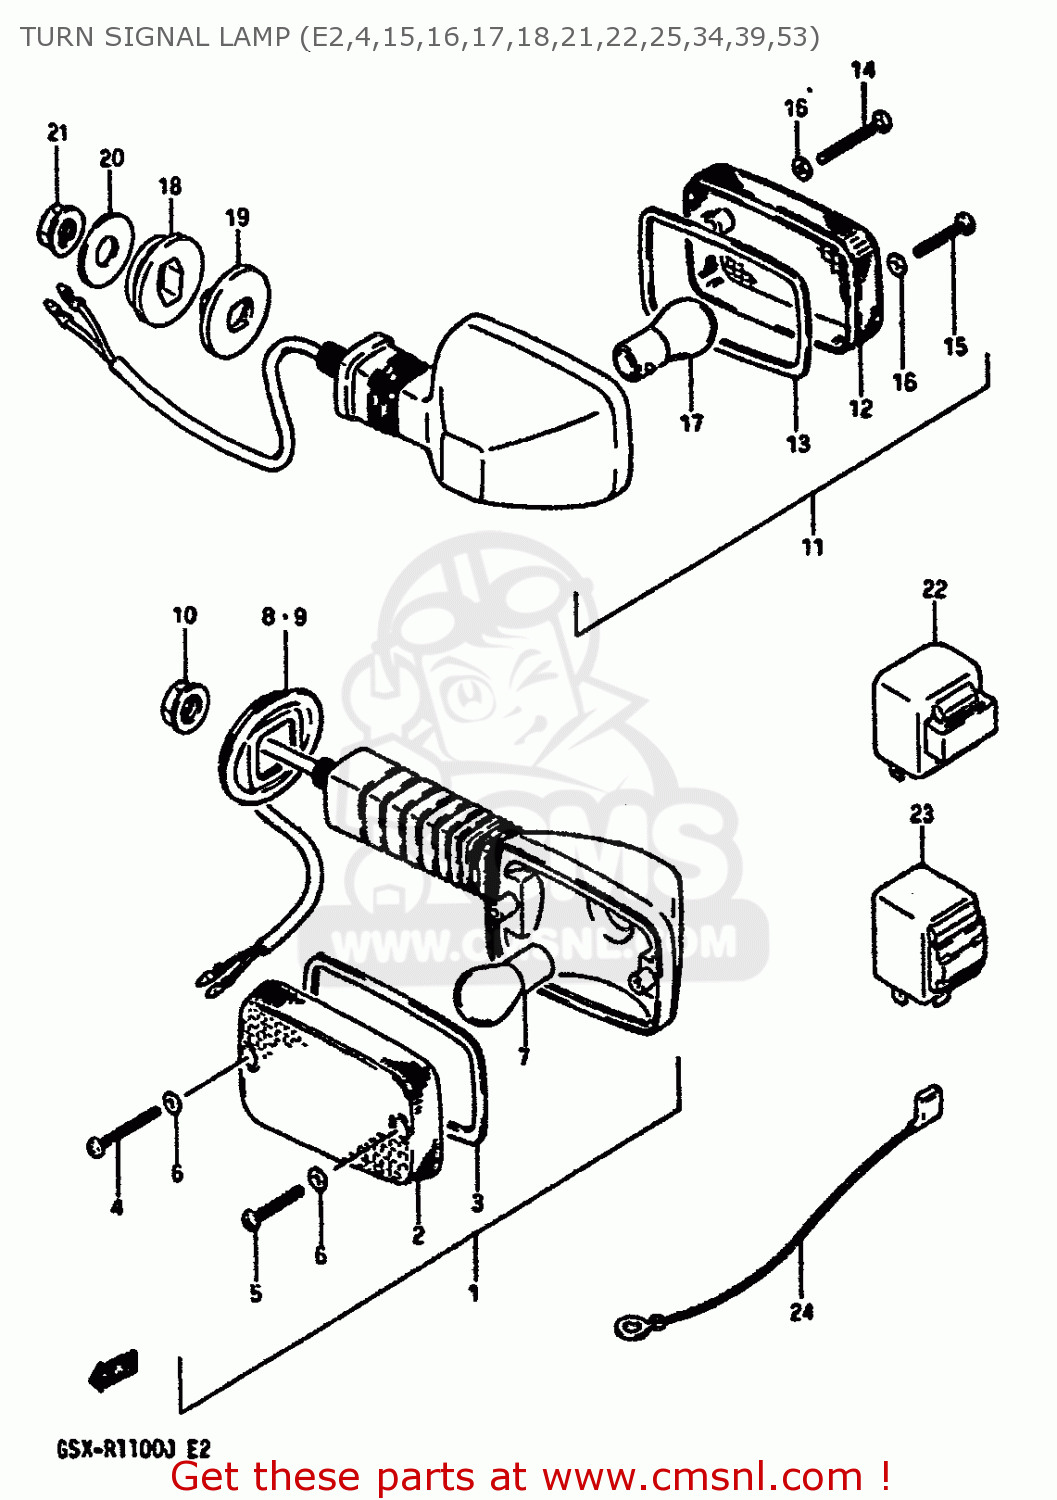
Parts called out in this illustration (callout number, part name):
1	LAMP ASSY, FRONT TURN SIGNAL
2	LENS,FR
3	GASKET (NAS)
4	SCREW,TURN SIG LENS FITTING
5	SCREW
6	GASKET
7	BULB(12V21W)
8	GROMMET, FRONT RH
9	GROMMET, FRONT LH
10	NUT
11	LAMP ASSY,REAR TURN SIGNAL
12	LENS,RR
13	GASKET (NAS)
14	SCREW,TURN SIG LENS FITTING
15	SCREW
16	GASKET (NAS)
17	BULB(12V21W)
18	CUSHION
19	SPACER
20	WASHER (10.2X27X1.6)
21	NUT
22	RELAY ASSEMBLY,TURN SIGNAL
23	RELAY ASSY,TUR
24	LEAD WIRE
